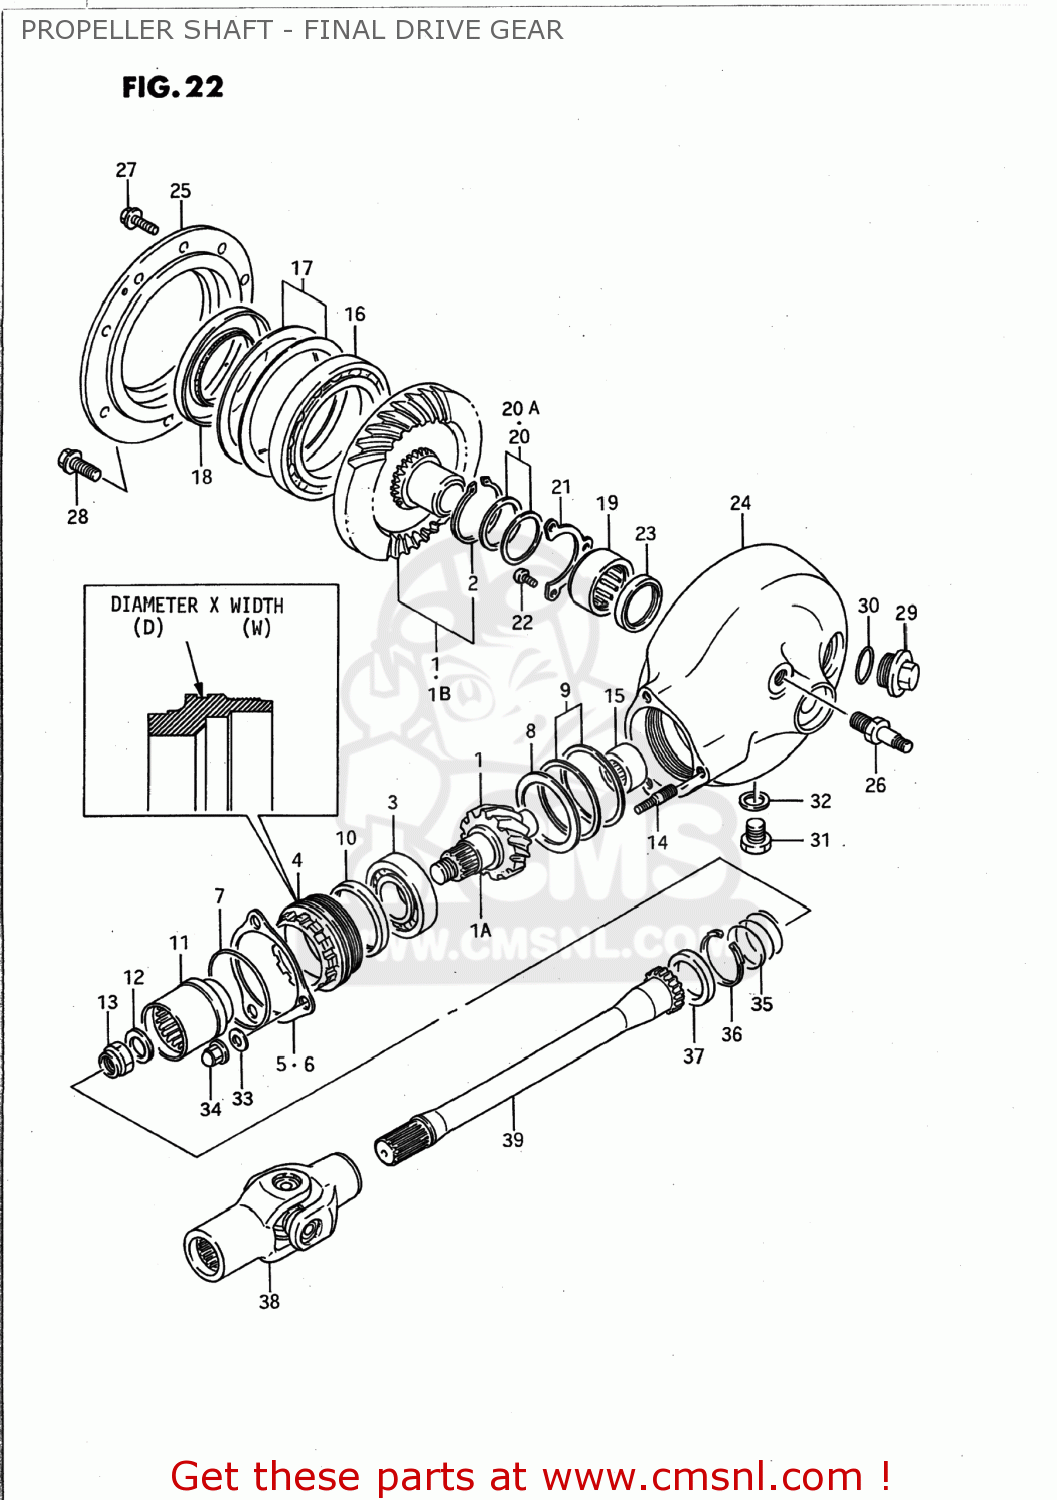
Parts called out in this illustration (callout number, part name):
1	GEAR & CASE SET,FINAL BEVEL
1A	GEAR,FINAL DRIVE BEVEL
1B	GEAR,FINAL DRIVEN BEVEL
2	.CIRCLIP
3	BEARING
4	STOPPER,FINAL DRIVE BEVEL
5	PLATE,BEARING STOPPER
6	PLATE,BEARING STOPPER
7	O RING(D:2.1,ID:66.2)
8	WASHER(54X68X1.5)
9	SHIM SET,FINAL DRIVE GEAR
10	OIL SEAL
11	COUPLING,FINAL DRIVE GEAR
12	WASHER(16X29X4)
13	NUT
14	STUD 10X25
15	BEARING(20X34X18)
16	BEARING(85X130X14)
17	SHIM SET,FINAL DRIVEN GEAR
18	SEAL,OIL(70X110X14.7)
19	BEARING(35X48X23.7)
20	WASHER(35X46X0.95)
20A	SHIM SET,FINAL DRIVEN
21	RETAINER,FINAL DRIVEN GEAR BRG
22	SCREW
23	SEAL,OIL(35X43X5)
24	CASE,FINAL GEAR
25	CASE,FINAL GEAR BEARING
26	BOLT,STUD
27	BOLT
28	BOLT
29	PLUG,30X9
30	O-RING
31	PLUG
32	GASKET(14X19.2X2) (NAS)
33	WASHER
34	NUT
35	SPRING
36	CIRCLIP
37	SEAL,OIL(30X40.5X5.5)
38	YOKE COMP,UNIVERSAL JOINT
39	SHAFT,PROPELLER
